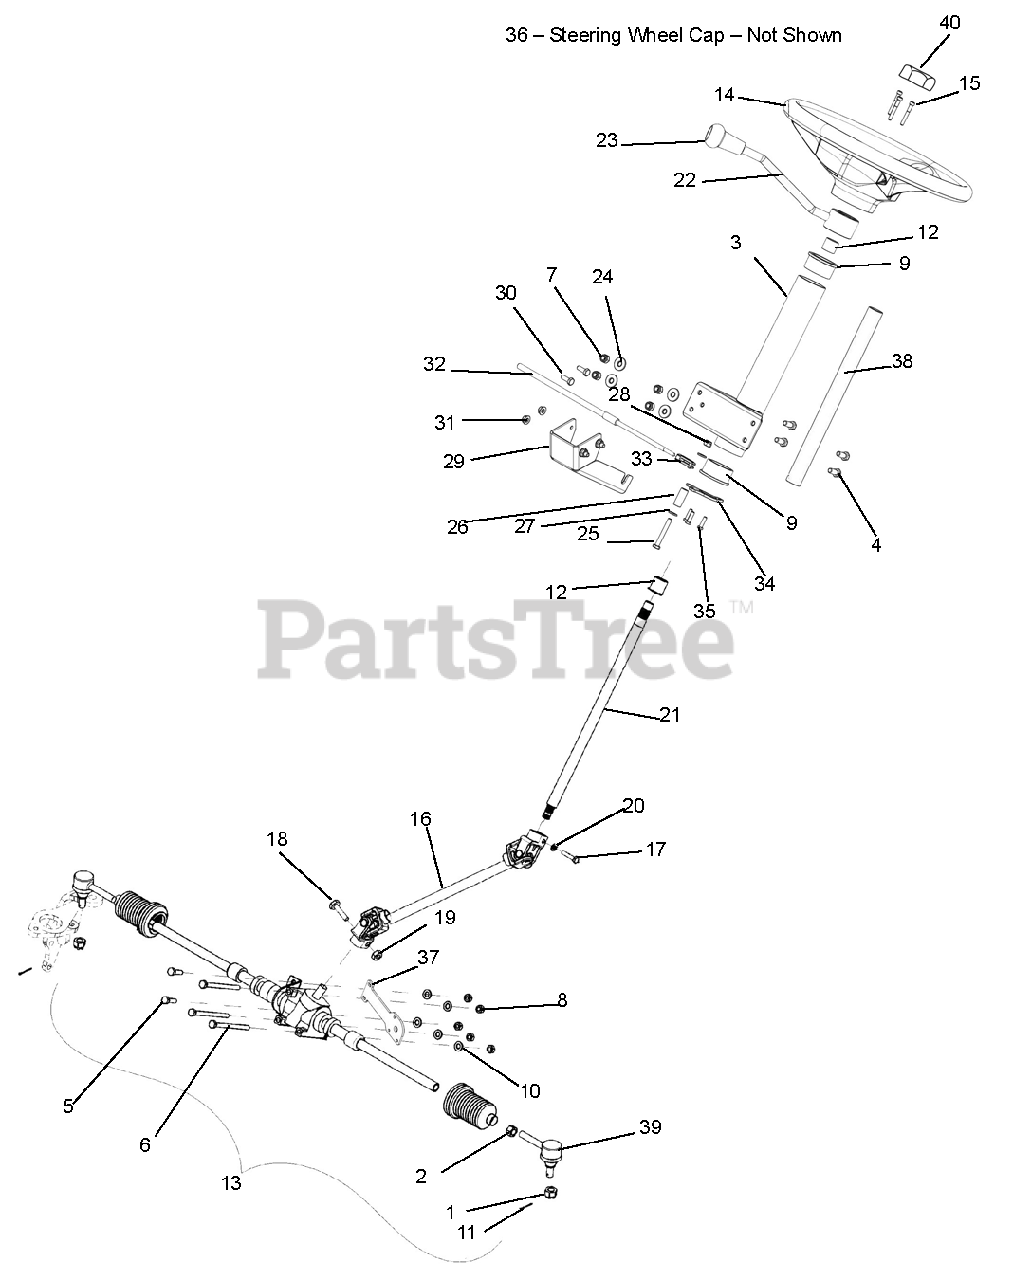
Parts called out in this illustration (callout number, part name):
1	NUT-HEX-SLOTTED M12X1.25 YWZC
2	NUT-HEX M14-1.50 GR8.8 YWZC
3	WLDT,STEERING COLUMN,BLK
4	@BLT-HEX .31-18X.75 GR5 YWZC
5	@BLT-HEX .31-18X1.50 GR5 YWZC
6	@BLT-HEX .31-18X4.50 GR5 YWZC
7	@NUT-LK-NYL .312-18 YWZC
8	@NUT-LK-TOP-FLG .31-18 YWZC
9	BUSHING, NYLON
10	@WSHR-FL-STL.38X.875X.083 YWZC
11	@PIN-CTR .09X1.00 EXTPRSQCT YZ
12	BUSHING, NYLON
13	RACK & PINION ST
14	STEERING WHEEL, 3 SPK CONTOUR
15	BOLT, 10-24X1.25 SOC GR5 Y
16	STEERING SHAFT TRUCK
17	MVL BOLT FOR 840-093C
18	HHCS M10X1.5X35 PLT
19	NUT-LK-NYL M10-1.5 YWZC
20	MVL SPRING WASHER FOR 840-093C
21	UPPER STEERING SHAFT TRUCK ASM
22	WLDT,COLUMN SHIFT LEVER
23	DASH SHIFTER KNOB
24	@WSHR-FL-STL.38X.875X.083 YWZC
25	@BLT-HEX .25-20X2.00 GR5 YWZC
26	SHIFT STOP
27	@WSHR-FL-STL.281X.62X.065 YWZC
28	@NUT-LK-NYL .250-20 YWZC
29	CABLE BRKT,SHIFTER,BLK
30	@BLT-HEX .25-20X.75 GR5 YWZC
31	@NUT-SPNLK-FLG .25-20 YWZC
32	SHIFT CABLE (DASH)
33	YOKE 10-32 W/ LOCK
34	CAM, COLUMN SHIFTER
35	SHCS #10-24 X .750
37	SPACER,STEERING
38	WLDT, COLUMN SHIFTER
39	TIE ROD END 826-399C
40	NUT HEX M16X2.00X8MM THK PLT
